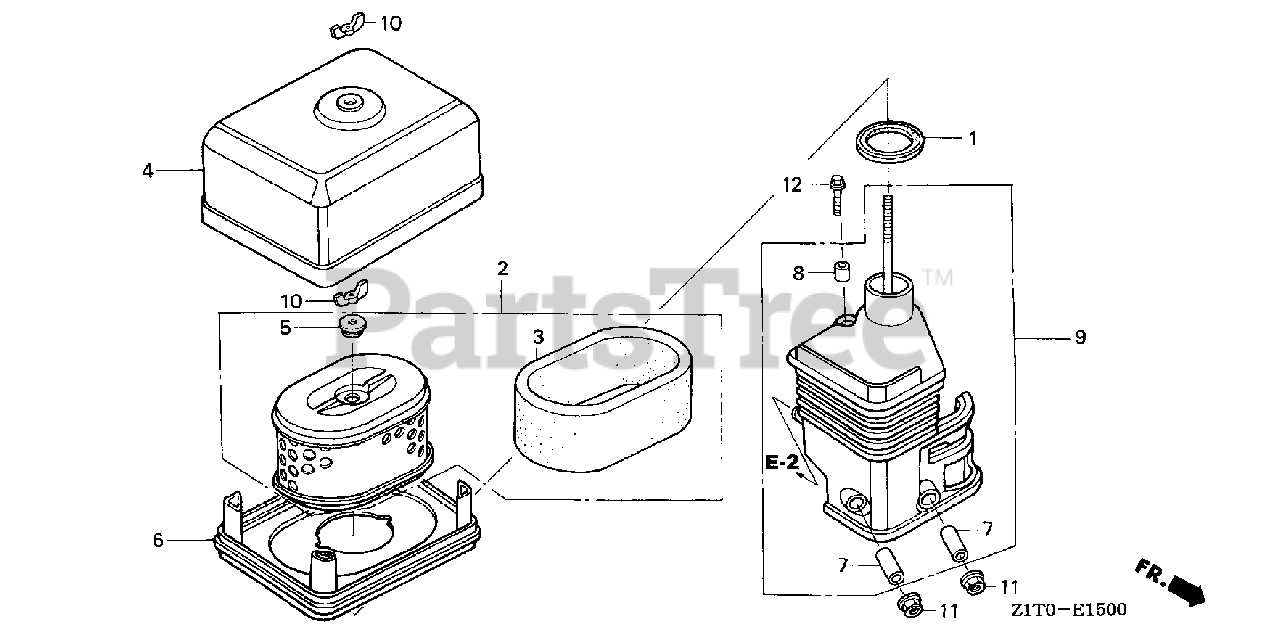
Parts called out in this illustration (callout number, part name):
1	GASKET, ELBOW
2	ELEMENT, AIR CLEANER (DUAL)
3	FILTER (OUTER)
4	COVER, AIR CLEANER (DUAL)
5	GROMMET, AIR CLEANER
6	NOSE, MUFFLER
7	COLLAR, AIR CLEANER
8	COLLAR B, AIR CLEANER
9	ELBOW, AIR CLEANER
10	NUT, TOOL BOX SETTING
11	NUT, FLANGE (6MM)
12	BOLT, FLANGE (6X20)
